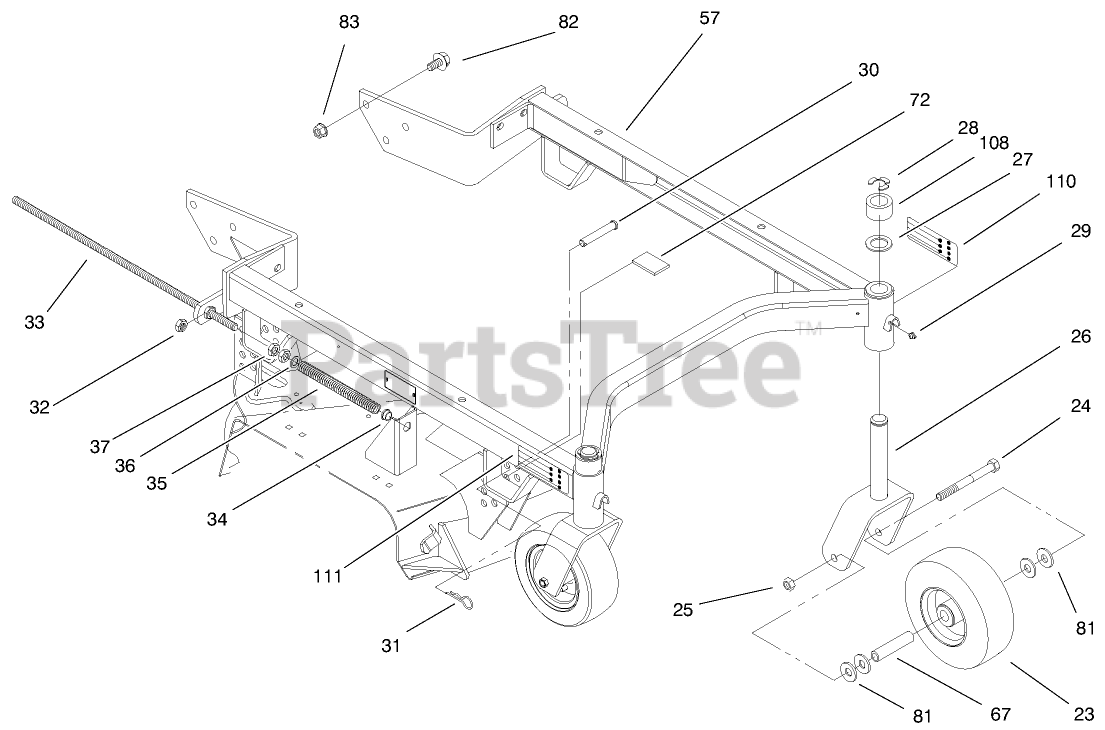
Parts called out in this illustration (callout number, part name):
23	CASTOR WHEEL ASM
24	SCREW-HH
25	NUT-HEX
26	Castor Fork
27	WASHER-THRUST
28	RING-RETAINING
29	FITTING-GREASE
30	PIN-CLEVIS
31	PIN-HAIR
32	NUT-LOCK, NI
33	SHAFT-ADJUSTING
34	BUSHING-FLANGE
35	SPRING
36	WASHER
37	NUT-JAM
57	FRAME ASM
67	SPANNER-TIRE
72	CUSHION-RUBBER
81	WASHER-FLAT
82	SCREW-HHF
83	NUT-HF
108	SPACER-CASTOR
110	DECAL-HOC, LH
111	DECAL-HOC, RH
